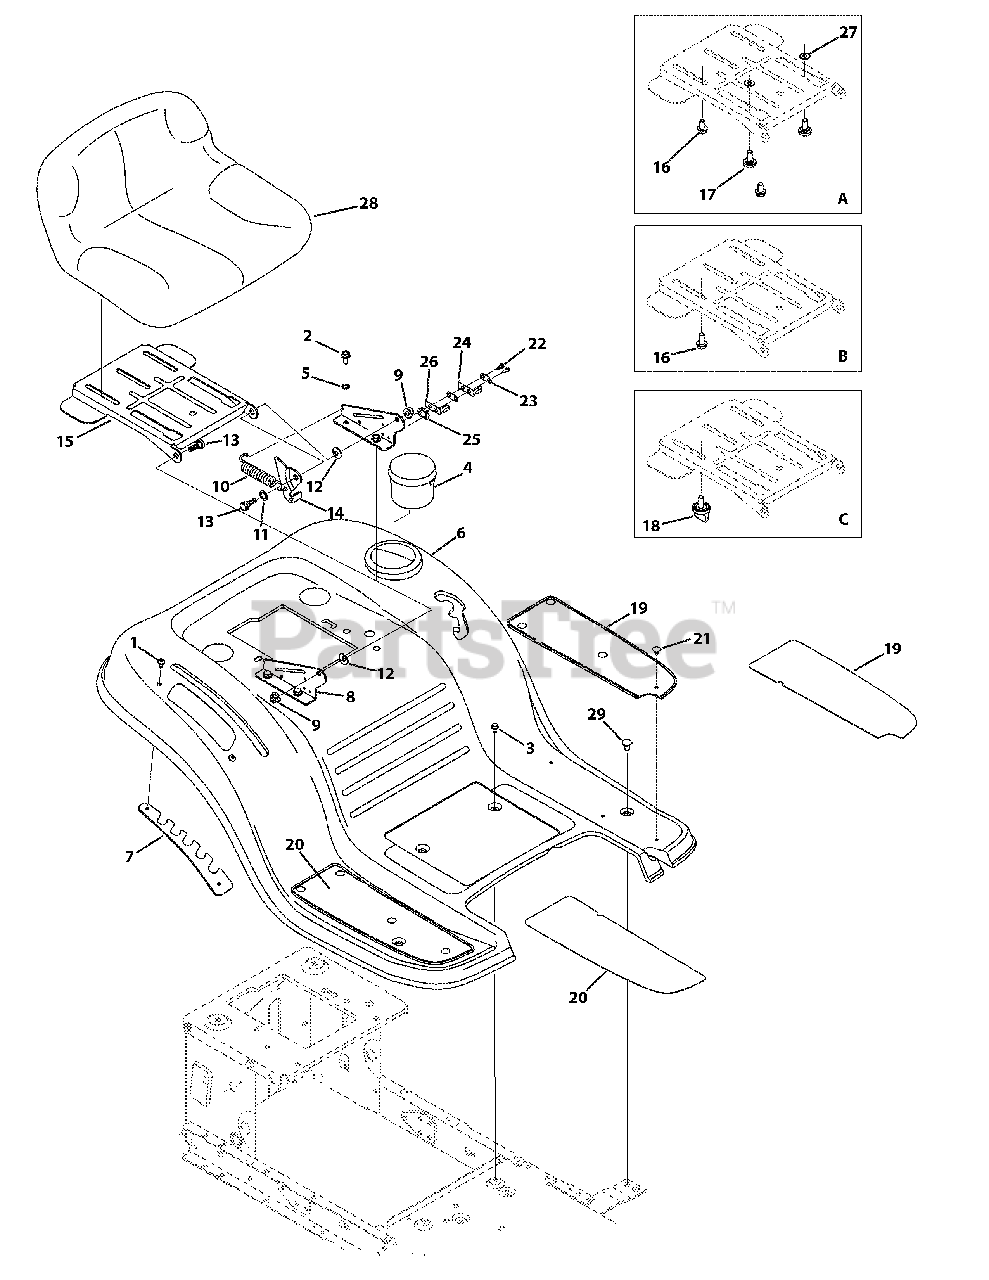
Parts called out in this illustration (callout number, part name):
1	Screw, 1/4-20 x .500
2	Screw, 5/16-18 x .750
3	Screw Pan Torx Head, 1/4-20 x .500
4	Cup Holder
5	Loack Washer, 5/16
6	Fender - Red
6	Fender - Yard Man Green
6	Fender - Black Jack
6	Fender - Mastercraft Green
7	Lift Adjuster Bracket - Powder Black
7	Lift Adjuster Bracket - Red
8	Seat Mount Bracket - Powder Black
8	Seat Mount Bracket - Red
9	Flangelock Nut, 5/16-18
10	Extension Spring
11	Flat Washer, .510x .750 x .033
12	Bell Washer, .340 x .872 x .060
13	Shoulder Screw, 5/16-18 x .437 x .268
14	Lift Seat Bracket
15	Pivot Seat Manual Adjust Bracket
16	Hex Head Flange, 3/8-16 x .875
17	Shoulder Screw, 3/8-16 x .625 x .145
18	Knob, 3/8-16 x .875
19	Foot Pad, LH
19	Foot Pad, Abrasive, LH
20	Foot Pad, RH
20	Foot Pad, Abrasive, RH
21	Ratchet Clip, .250 x .500
22	Screw, 8-18 x .500
23	Insulator Plate
24	Outer Seat SPring
25	Insulator Boss Plate
26	Inner Seat Spring
27	Flat Washer, .385 x .62 x .063
28	Medium Back Seat, Set-up A
28	Medium Back Seat, Black, Figure B
28	Medium Back Seat, Yellow, Figure B
28	Low Back Seat, Black, Figure B or C
28	Low Back Seat, Yellow, Figure B
28	High Back Seat, Black, Figure B
29	Screw Carriage, 1/4-20 x .62
